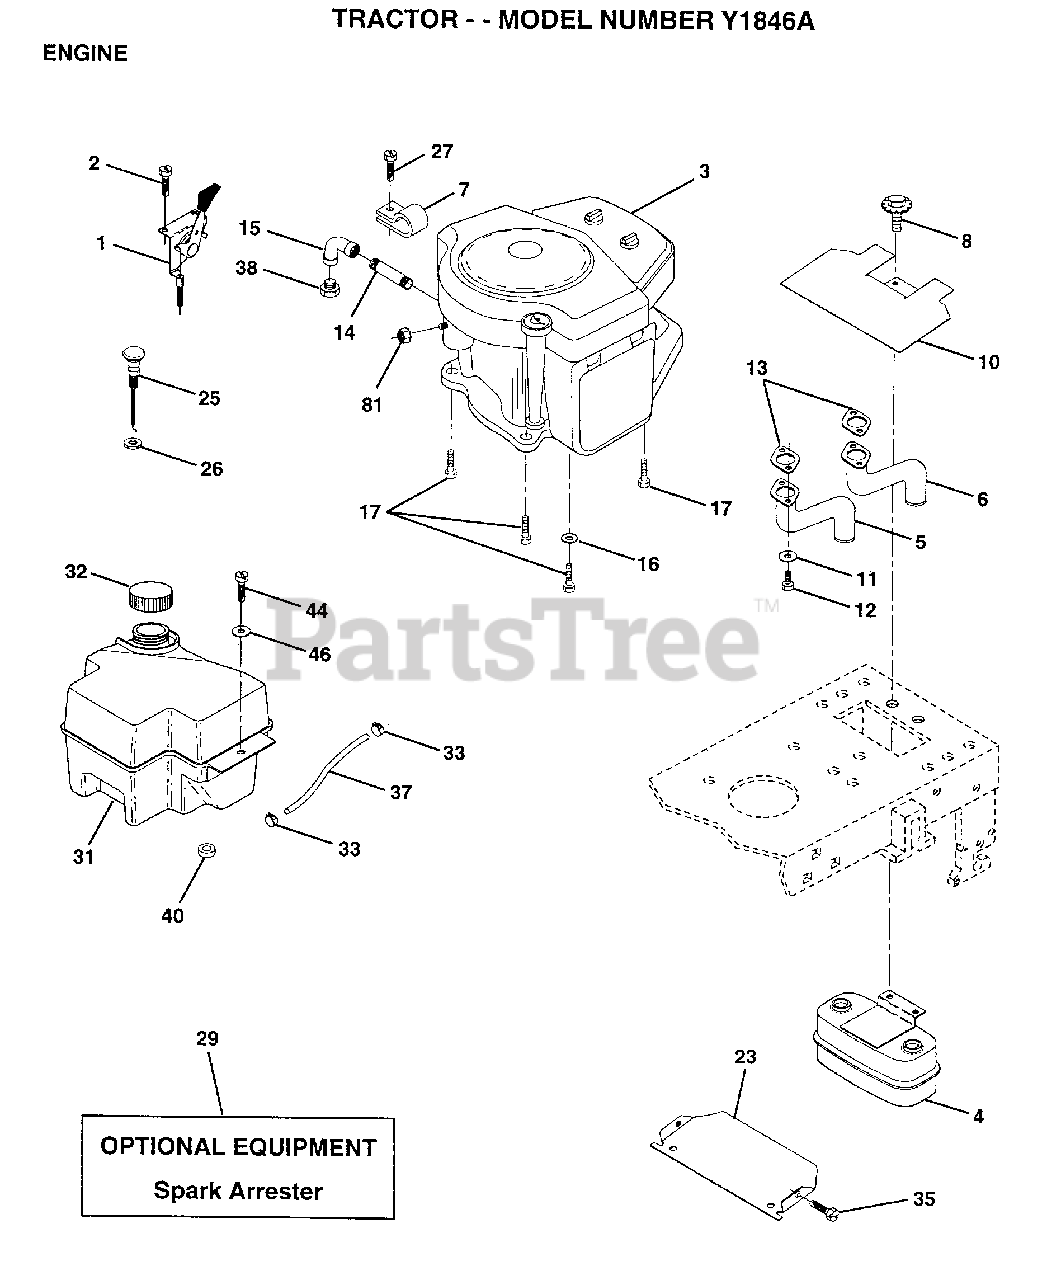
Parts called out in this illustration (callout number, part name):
1	SCREW.1/4-20X1/2
3	ENG B&S 10-12.5HP PWRBLT DC
4	SCREW
5	LOCKWASHER
6	GASKET ENG 1 313 LD TIN PLATED
7	LOCKWASHER
8	BOLT T
10	LOCKWASHER
12	MUFFLER
13	DEFLECTOR.222573
16	"STOP,DASH THROTT"
17	SCREW LT
39	NUT
